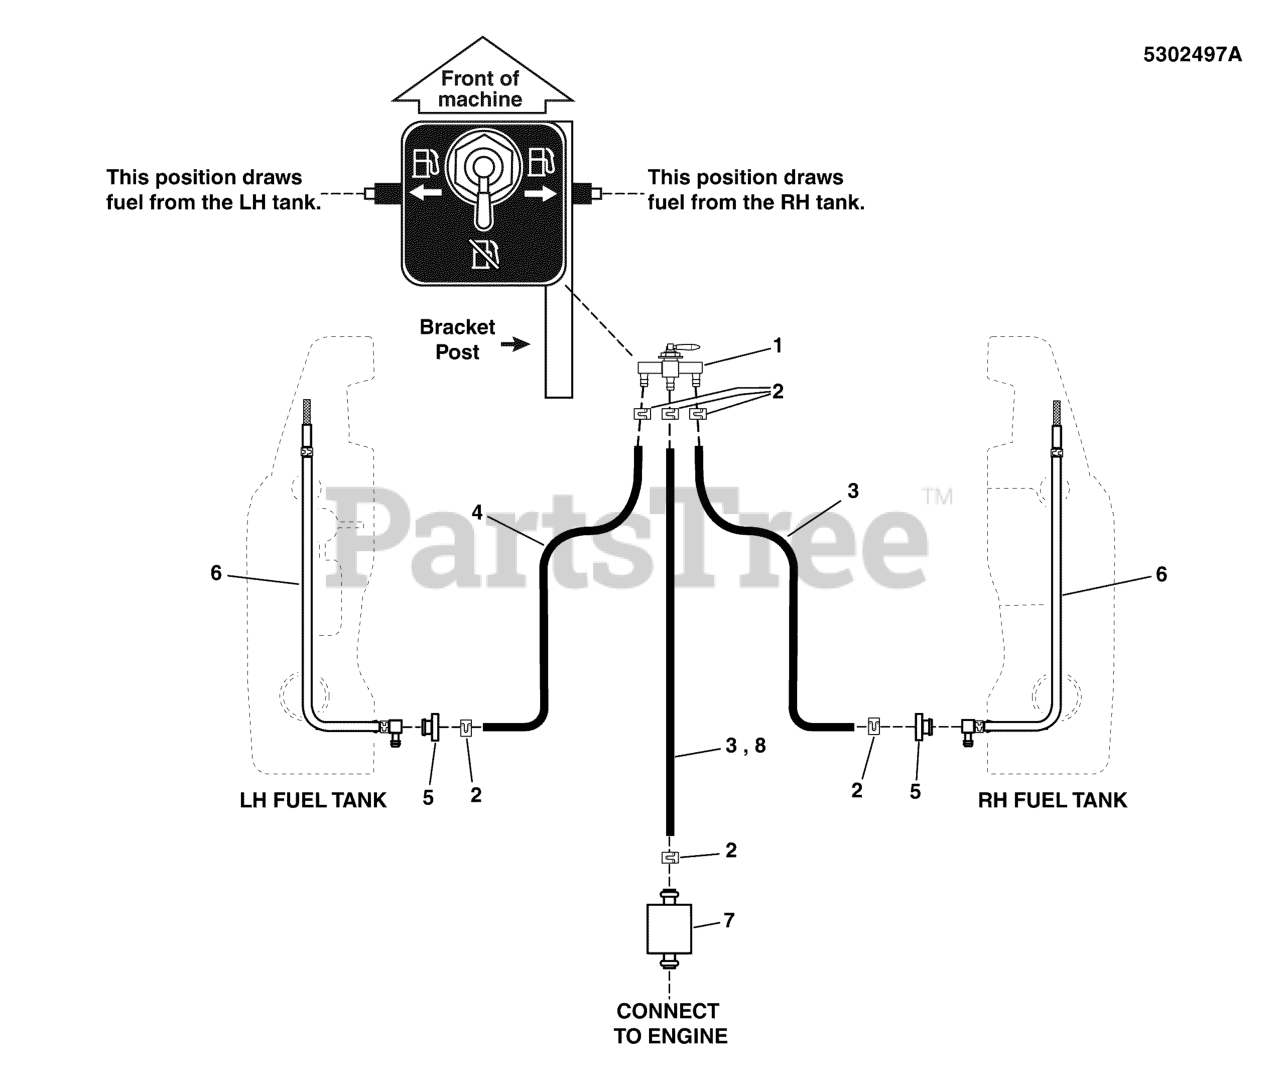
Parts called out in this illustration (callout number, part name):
1	VALVE, FUEL SHUT-OFF, 11772
2	CLAMP, HOSE, EXTERNAL, 1/2 - RED
3	HOSE, 1/4" FUEL, 19.00"
4	HOSE, 1/4" FUEL, 40.00"
5	BUSHING-FUEL TANK RED RUBBER
6	PICK UP TUBE ASSEMBLY, FUEL LINE (SV)
7	FUEL FILTER (SV)
8	HOSE, 1/4" FUEL, 25.00"
